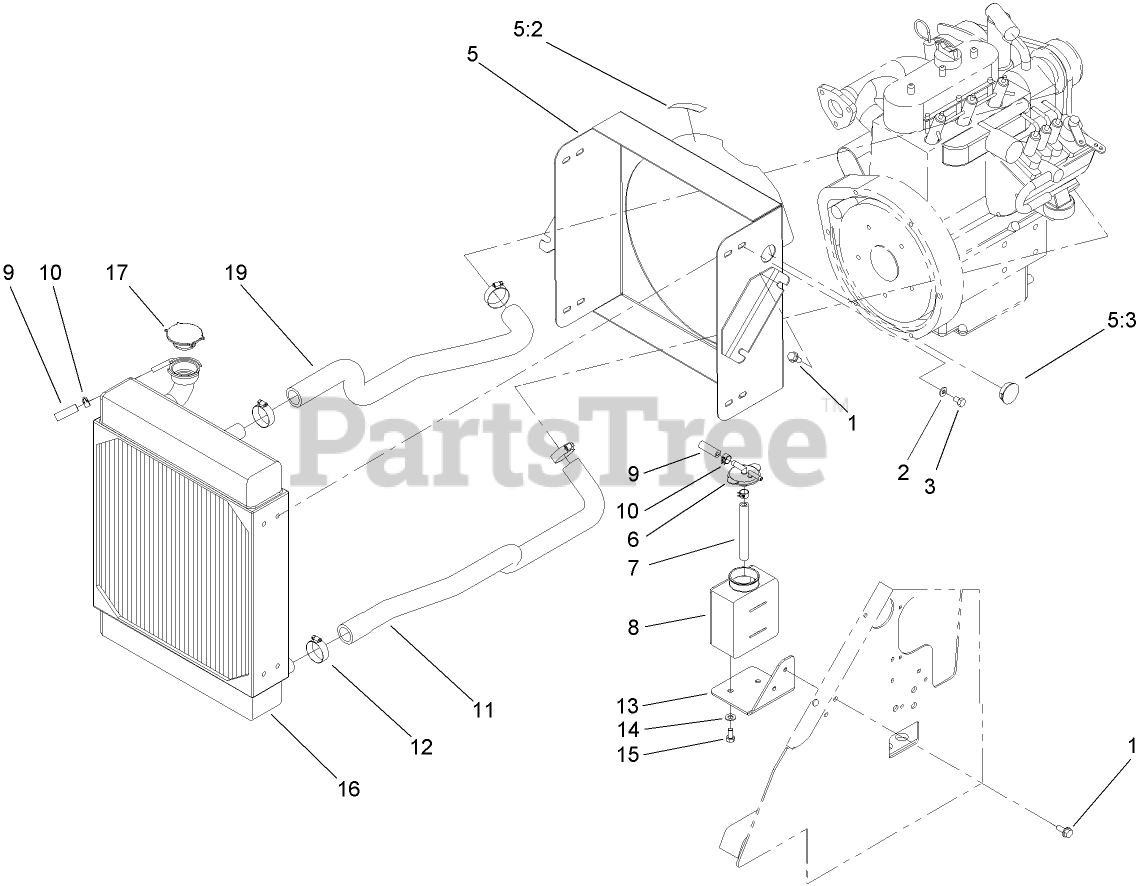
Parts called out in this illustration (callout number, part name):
1	SCREW-HWHTF
2	WASHER-FLAT
3	SCREW-HH
5	MOUNT-RADIATOR
5:2	DECAL-WARNING, FAN
5:3	PLUG-HOLE
6	CAP-TANK, OVERFLOW
7	HOSE-FUEL
8	TANK-OVERFLOW
9	HOSE-FUEL
10	CLAMP-HOSE
11	HOSE-RADIATOR, LOWER
12	CLAMP-HOSE
13	MOUNT-TANK, OVERFLOW
14	WASHER-PLAIN
15	BOLT
16	RADIATOR
17	CAP-RADIATOR
19	HOSE-RADIATOR, UPPER
